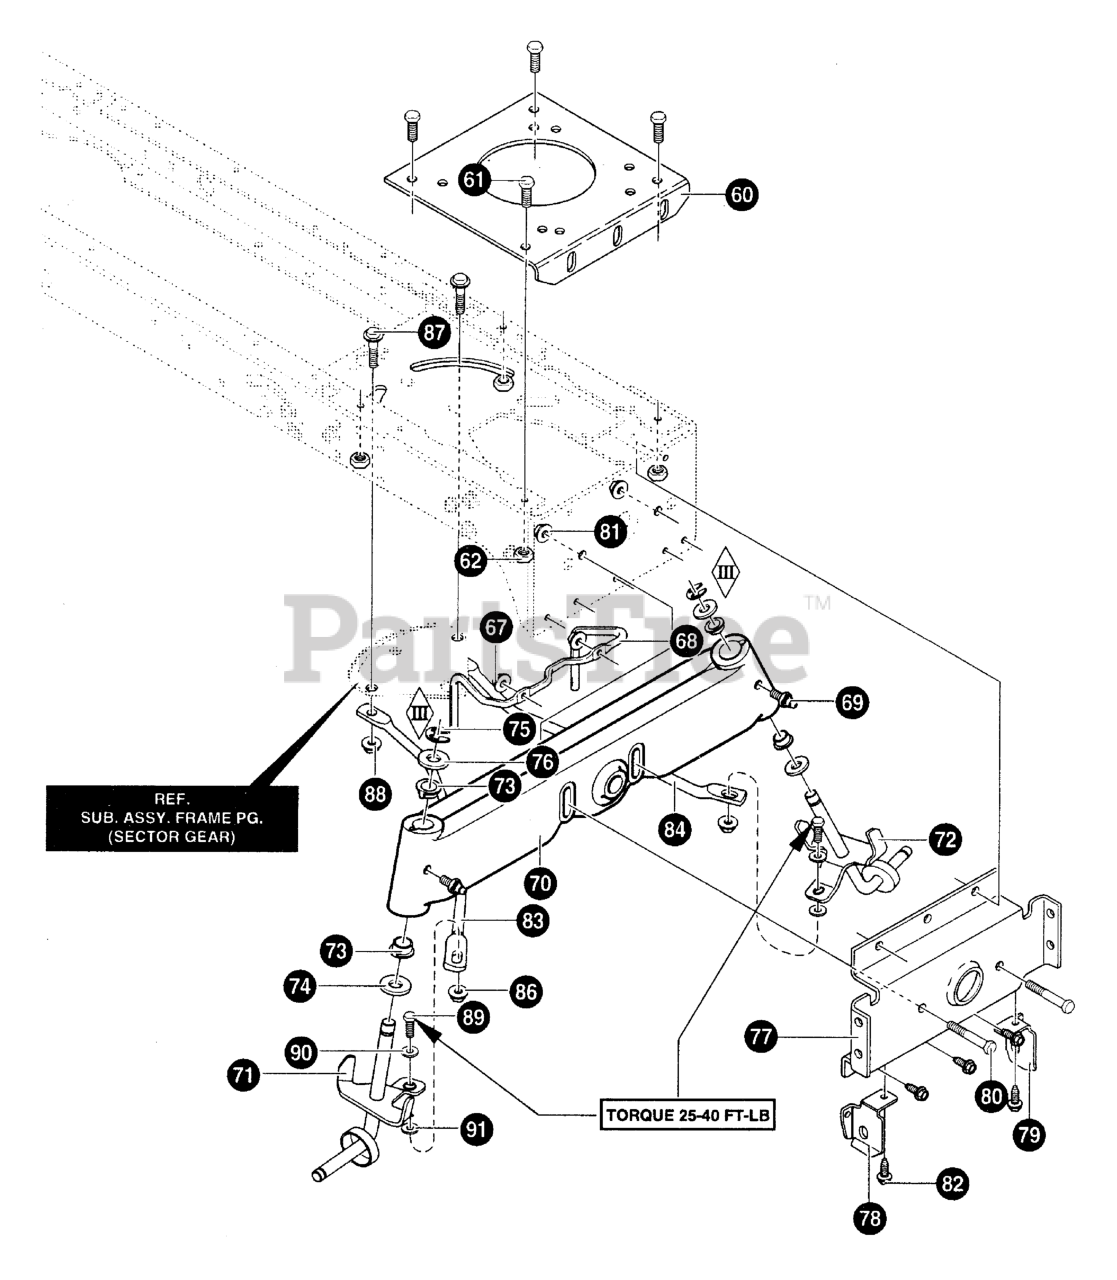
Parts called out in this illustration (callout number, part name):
60	ENGINE PLATE
61	SCREW, 5/16-18 x 0.75 HHWATAP
62	NUT, 5/16-18 WDFLLK 15X88
67	NUT, 5/16-18 HEXWDFLLK WHIZ
68	GUIDE-STACK PULLEY BELT
69	ZERK, GREASE FITTTING
70	AXLE, CAST MACHINED REBA
71	SPINDLE, LONG RH
72	SPINDLE, LONG LH
73	BEARING, SPINDLE
74	WASHER, .766IDX1.62ID
75	E-RING.574IDX.050/.750SH 11X3
76	WASHER, FLAT .765 x 1.81 x .059
77	HANGER, AXLE
78	HANGER, DECK RH
79	HANGER, DECK LH
80	SCREW, 5/16-18 x 3.00
81	NUT, 5/16-18 WDFLLK 15X88
82	SCREW, 5/16-18 x 0.75 HHWATAP
83	DRAG LINK RH
84	DRAG LINK LH
86	NUT, 3/8-16 HWDFLLK MACK 15X84
87	SHOULDER BOLT 9X57
88	NUT, 3/8-16 HWDFLLK MACK 15X84
89	SCREW, 3/8-16 x 1.50
90	WASHER FLAT .391 X1.00X.083
91	WASHER FLAT .406X.81 X16GA
